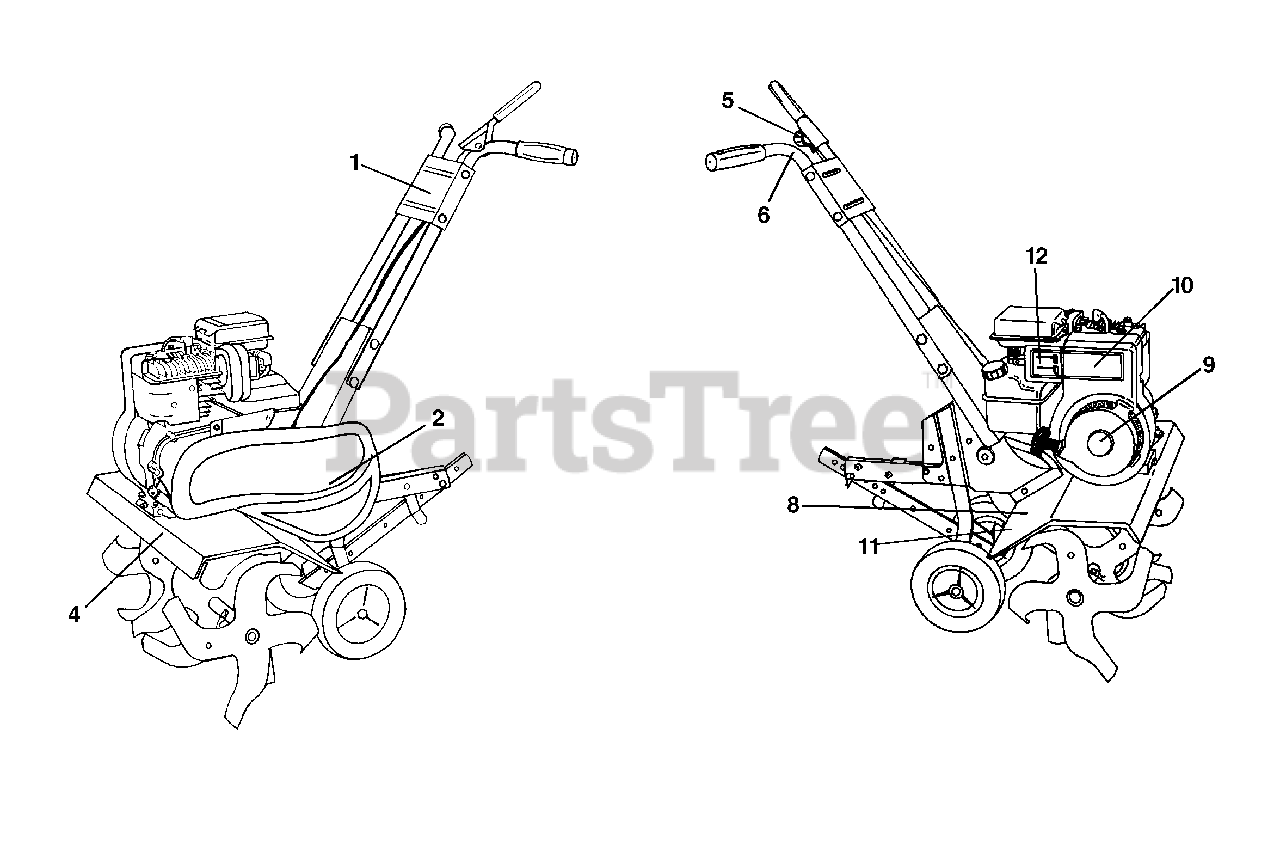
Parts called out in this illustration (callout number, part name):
1	Decal, Logo
2	Decal, Logo
4	Decal, Description
5	Decal, Tine Control
6	Decal, Hand Placement
8	Decal, Warning, Rotating Tines
9	Decal, Briggs & Stratton
10	Decal, 3.5 HP
11	Decal, Warning
12	Decal, Speed Control
